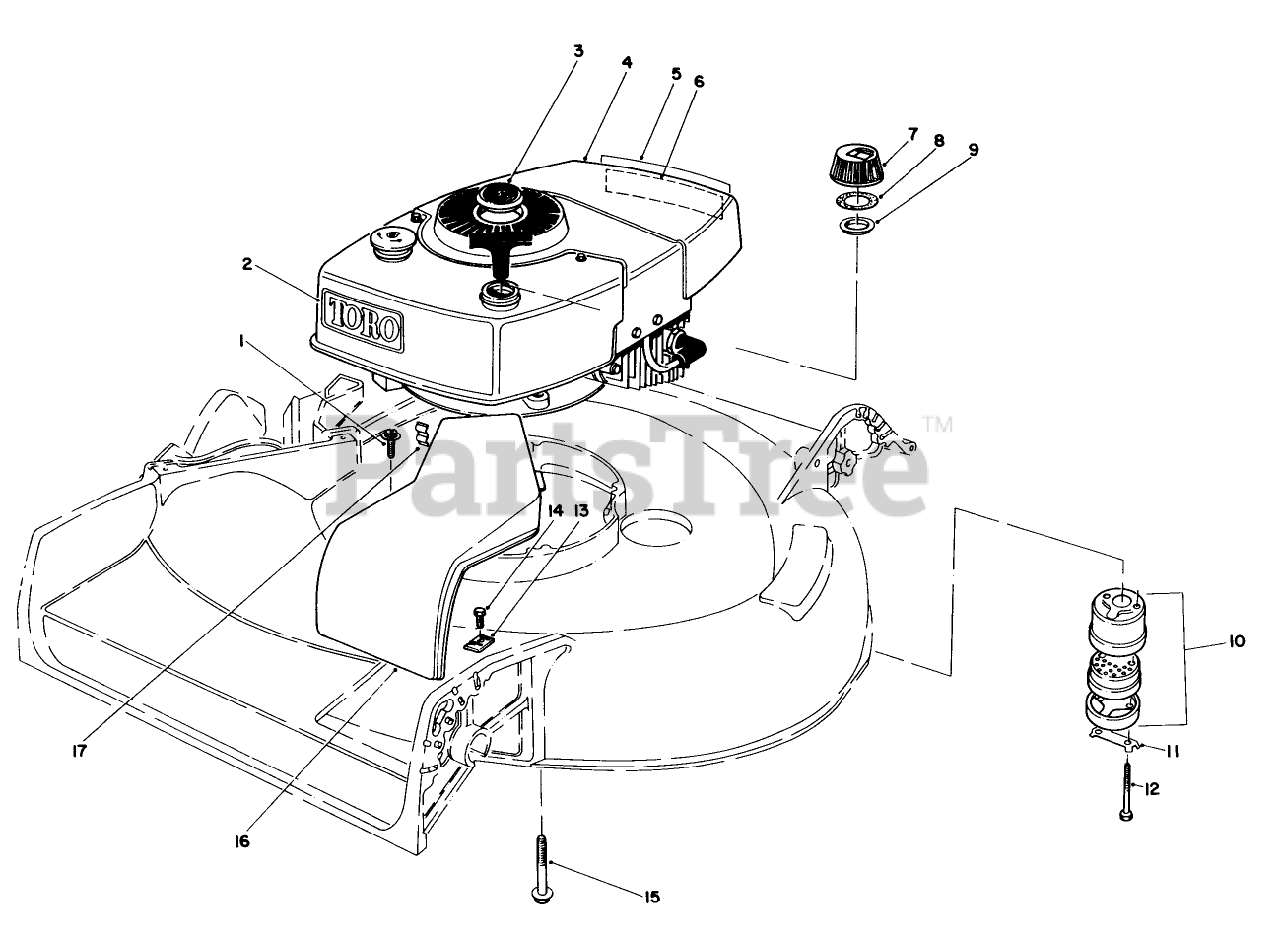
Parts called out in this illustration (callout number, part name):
1	SCREW
4	Engine
8	GASKET
10	MUFFLER ASM
11	CLIP - LOCKING
12	SCREW-HH
14	SCREW-THD ROLL, HWH
15	3/8-16 X 2-3/4 CAPSCR
